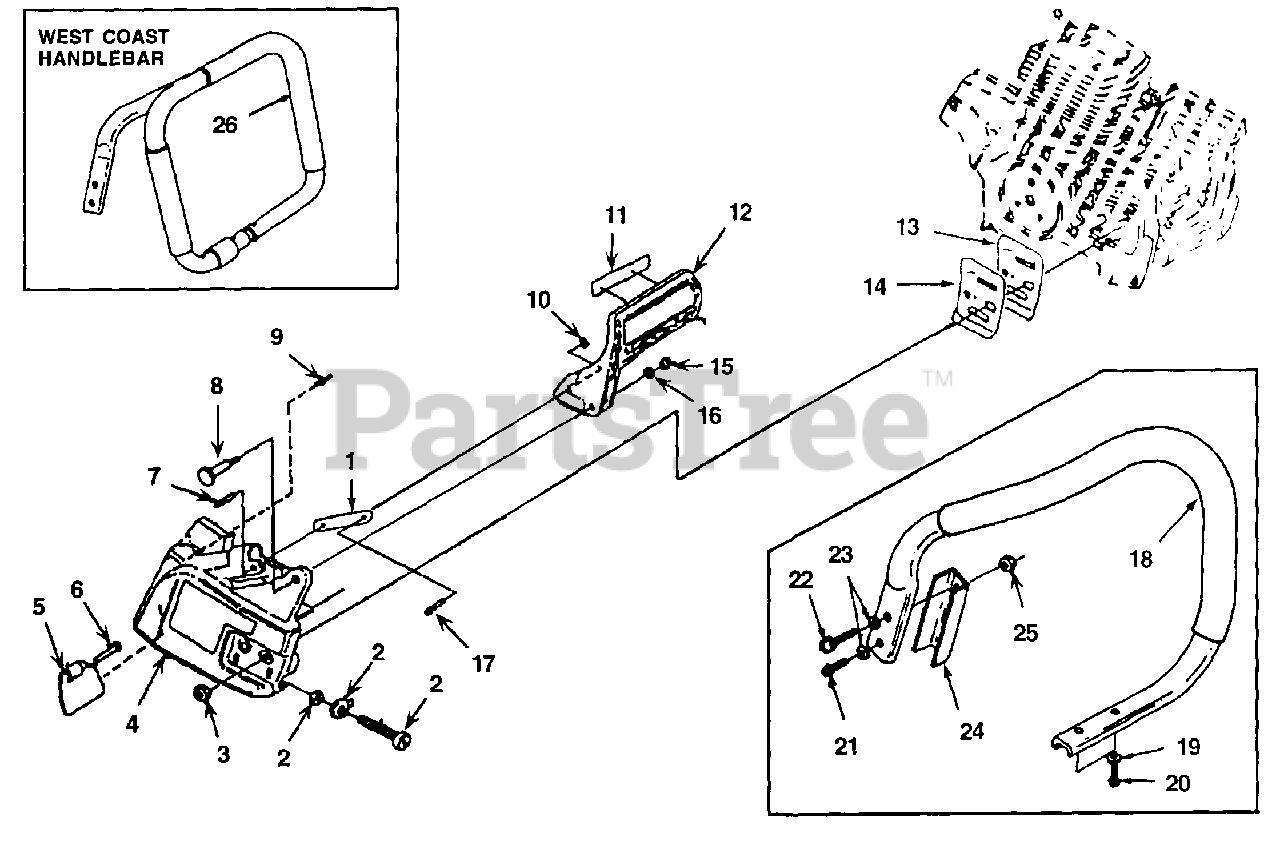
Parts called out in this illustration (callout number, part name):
1	HAND GUARD LINK
2	GUIDE BAR ADJ. KIT
3	NUT - HEX (10-24)
4	COVER - DRIVE CASE
5	SAWDUST SHIELD
6	RIVET - PAN HO (.187 X .381)
7	PIN (5M X 16MM)
8	SCREW - SHOULDER (M5)
9	PIN - SHOULDER DOWEL
10	RING - SNAP
11	DECAL - HANDGUARD
12	HANDGUARD
13	PLATE - G/BAR (INNER)
14	PLATE - G/BAR (OUTER)
15	NUT (5MM)
16	WASHER - BELLEVILLE (12MM)
17	PIN - (.156 DIA)
18	HANDLE BAR (Flush Cut)
19	WASHER - Conical (#10)
20	SCREW - Socket Cap (10-32 X 5/8")
21	SCREW - Socket Cap (10-24 X 3/4")
22	SCREW - Socket Cap (10-32 X 7/8")
23	WASHER - Conical (#10)
24	NEST KIT
25	NUT - Lock (#10)
26	HANDLE BAR (West Coast)
